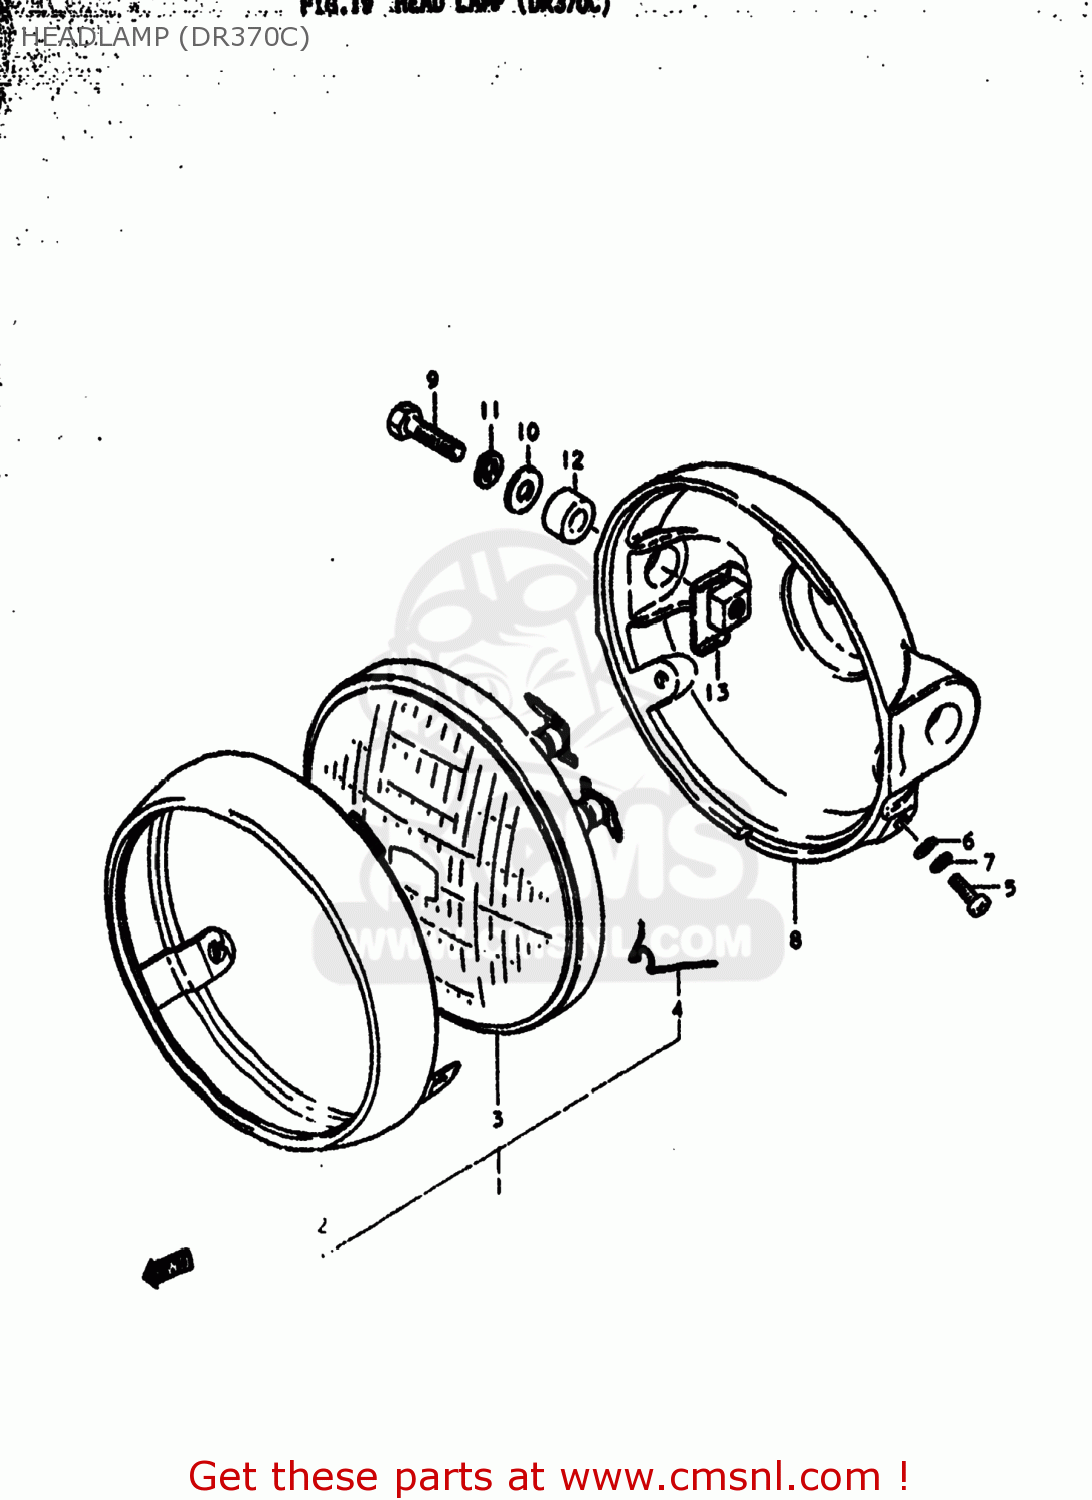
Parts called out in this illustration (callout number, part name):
1	LAMP ASSEMBLY,HEAD
2	RIM,HEADLAMP
3	LAMP UNIT
4	SPRING,HEADLAMP UNIT
5	SCREW
6	WASHER
7	LOCK WASHER
8	HOUSING,HEADLAMP
9	BOLT
10	WASHER
11	LOCK WASHER
12	SPACER (8.8X12X7)
13	PLATE,HEADLAMP HOUSING
